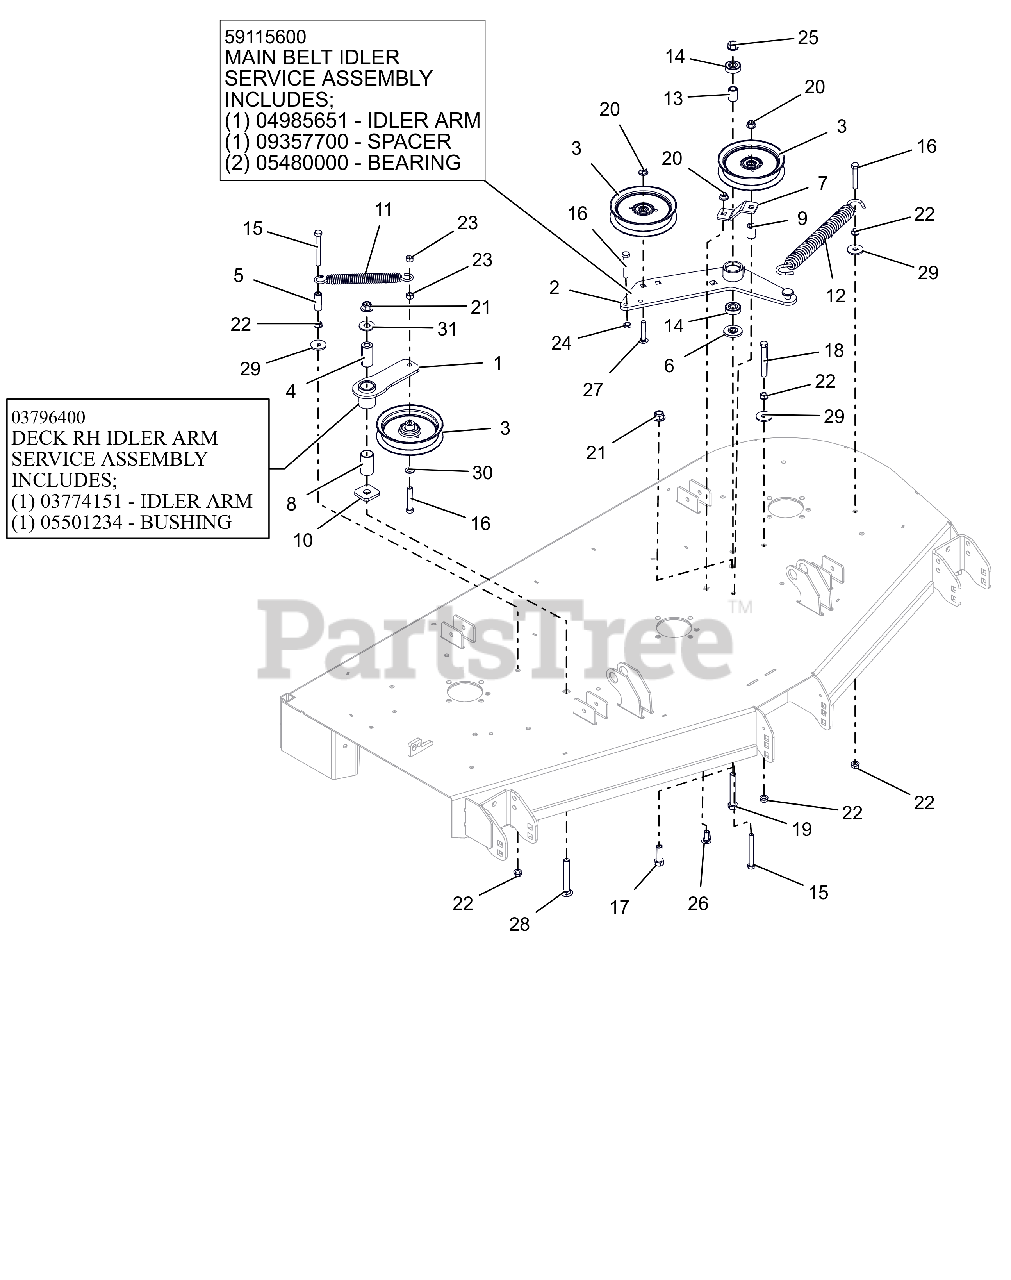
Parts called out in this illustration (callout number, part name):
1	WMT, IDLER ARM - BLACK
1	ASM, IDLER ARM (DECK)
2	DECK PTO IDLER ARM WLDMT - BLK
2	ASSEMBLY, MAIN BELT IDLER
3	IDLER, FLAT 5.00"
4	BSHG, SPCR .502X.997X2.03 PM
5	SPACER, .375IDX.625ODX1.66 PM
6	SPACER, IDLER ARM
7	PTO FIXED IDLER MTG BRKT -RED
8	BSHG, 1.00X1.125X1.937
9	BUSHING, SLV .380X.750X1.190
10	WSHR-FLT .640X1.75X.250
11	SPRING, EXTENSION
12	SPRING, EXTENSION
13	SPACER .510 X .75 X 1.1485
14	BRG-BALL .500X1.38X.437
15	BLT, HEX .38-16X3.25 G5 ZCC
16	BLT,HEX .38-16X2.25 G5 ZCC
17	BLT,HEX .50-13X1.50 G5 ZCC
18	BLT, HEX .38-16X3.25 G5 ZCC
19	BLT, HEX .50-13X3.00 G5 ZCC
20	NUT,NYL-FLG .38-16 GF ZCC
21	NUT,NYL-FLG .50-13 GF ZCC
22	NUT, SPNLK-FLG .38-16 G5 ZCC
23	NUT-LK-CTR .38-16 ZC120
24	NUT-JAM .375-16 G2 ZCC
25	NUT-LK-CTR-FLG .500-13 GG ZCC
26	BLT,RHSSN .38-16X1.00 G5 ZCC
27	BLT,RHSSN.375-16X2.00 G5 ZCC
28	BLT, RHSN .50-13X3.50 G5 ZCC
29	WSHR,FLT .406X1.375X.135 ZCC
30	WSHR,FLT .406X.812X.065 ZCC
31	WSHR,FLT .563X1.375X.109 ZCC
